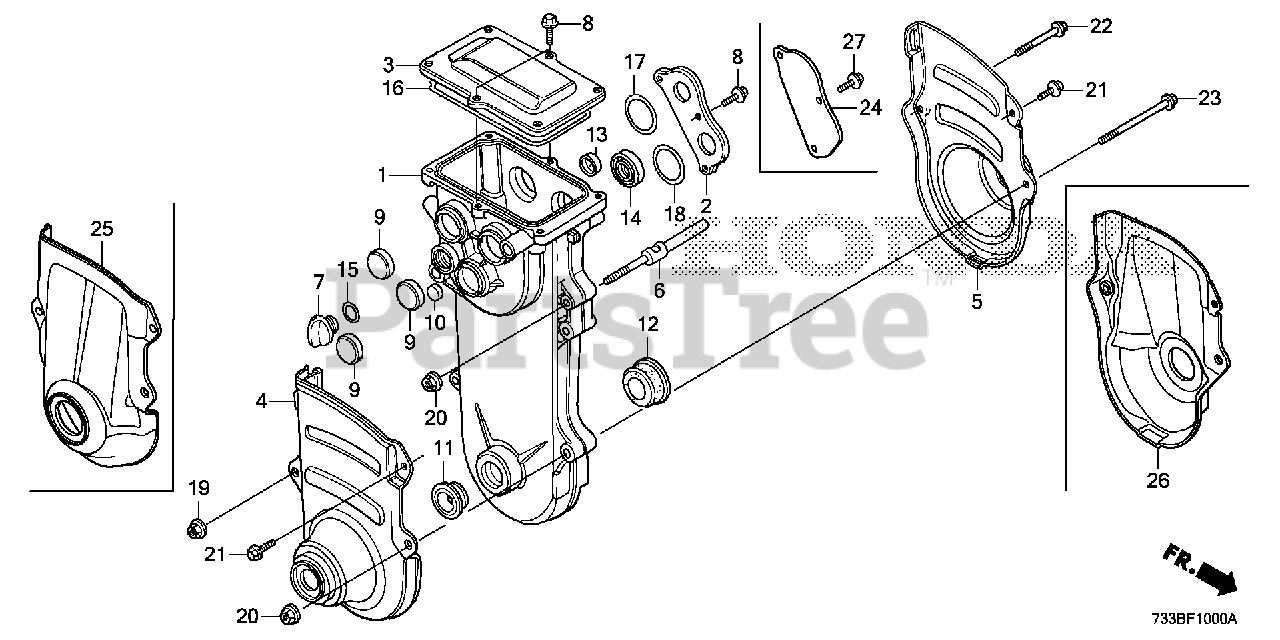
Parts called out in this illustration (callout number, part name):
1	CASE, TRANSMISSION
2	PLATE, BEARING HOLDER
3	COVER, TRANSMISSION CASE TOP
4	PROTECTOR, R. TRANSMISSION CASE
5	PROTECTOR, L. TRANSMISSION CASE
6	SHAFT, TENSIONER ARM
8	BOLT, FLANGE (6X12) (CT200)
9	PLUG, SEALING (28) (ARAI)
10	PLUG, SEALING (16) (ARAI)
11	SEAL, WATER (32X52X10.5) (NOK)
12	SEAL, WATER (32X58X10.5) (NOK)
13	PLUG, SEAL
14	OIL SEAL (15X35X7) (ARAI)
15	O-RING (16MM)
16	O-RING A, TRANSMISSION CASE
17	O-RING (40.5X2.5) (ARAI)
18	O-RING (45.5X2.5) (ARAI)
19	NUT, FLANGE (6MM)
20	NUT, FLANGE (8MM)
21	BOLT, FLANGE (6X10)
22	BOLT, FLANGE (6X40)
23	BOLT, FLANGE (8X55)
